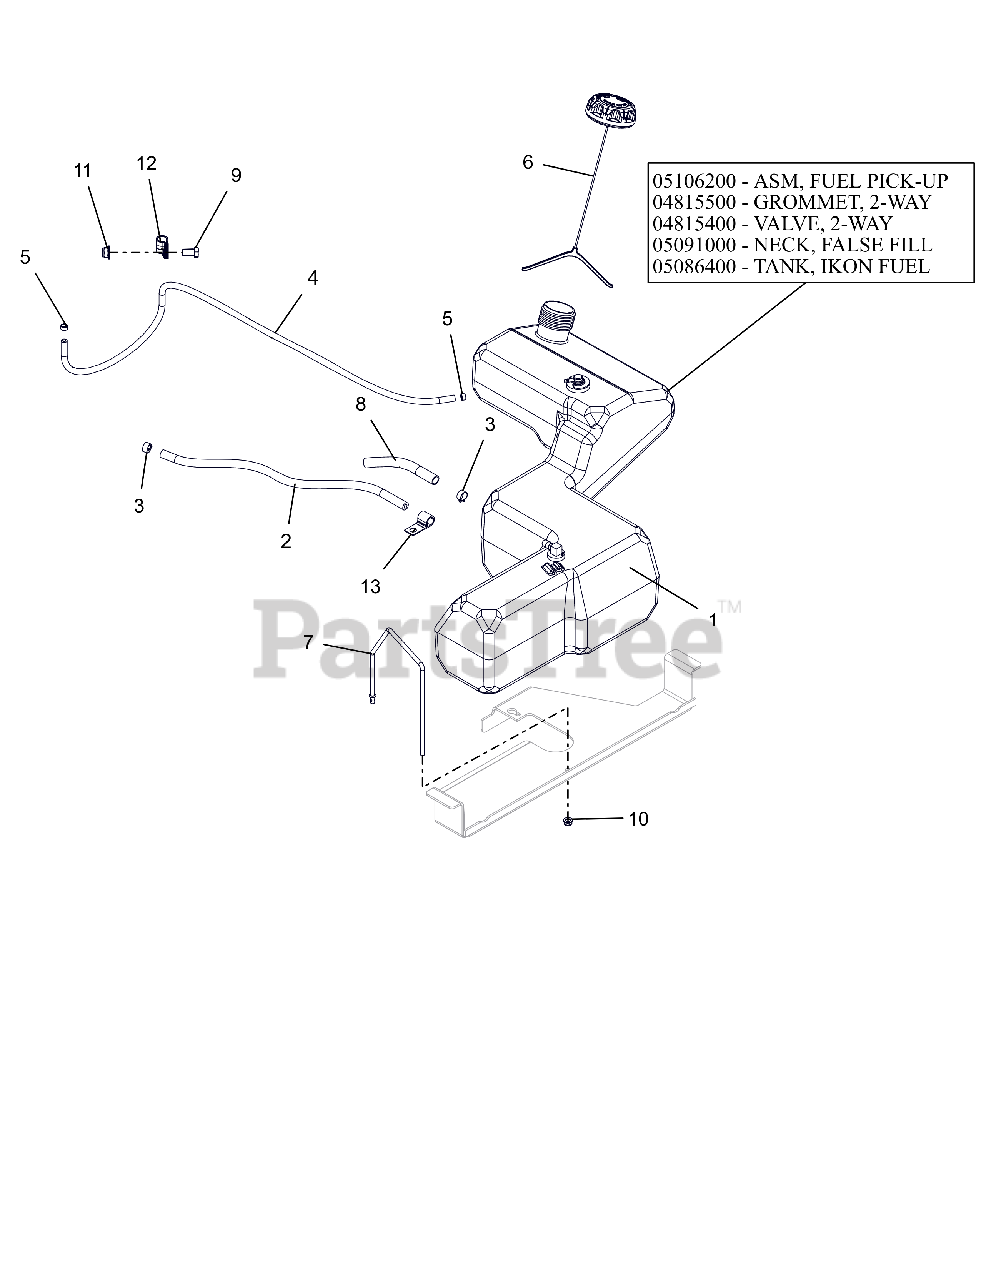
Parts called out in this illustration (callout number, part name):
1	ASSEMBLY, FUEL TANK IKON(2017)
1	ASM, IKON FUEL PICK-UP
1	GROMMET, 2-WAY
1	VALVE, 2-WAY
1	NECK, FALSE FILL-2017 IKON
1	TANK, IKON FUEL (2017)
2	HOSE, .25 LOW-PERM BULK GAS
3	CLAMP, FUEL LINE
4	HOSE, .188 LOW-PERM BULK GAS
5	CLAMP-HOSE, SPRING .188
6	CAP, FUEL VENT-IN 2.25" RATCH.
7	BRKT, FUEL TANK HOLD DOWN
8	WRAP, ANTIABRASION .5X.064WALL
9	@BLT-HEX .38-16X.75 GR5 YWZC
10	@NUT-LK-NYL-FLG .25-20 YWZC
11	@NUT-LK-NYL-FLG .38-16 YWZC
12	CLAMP, CUSHIONED STEEL
13	J-CLAMP
